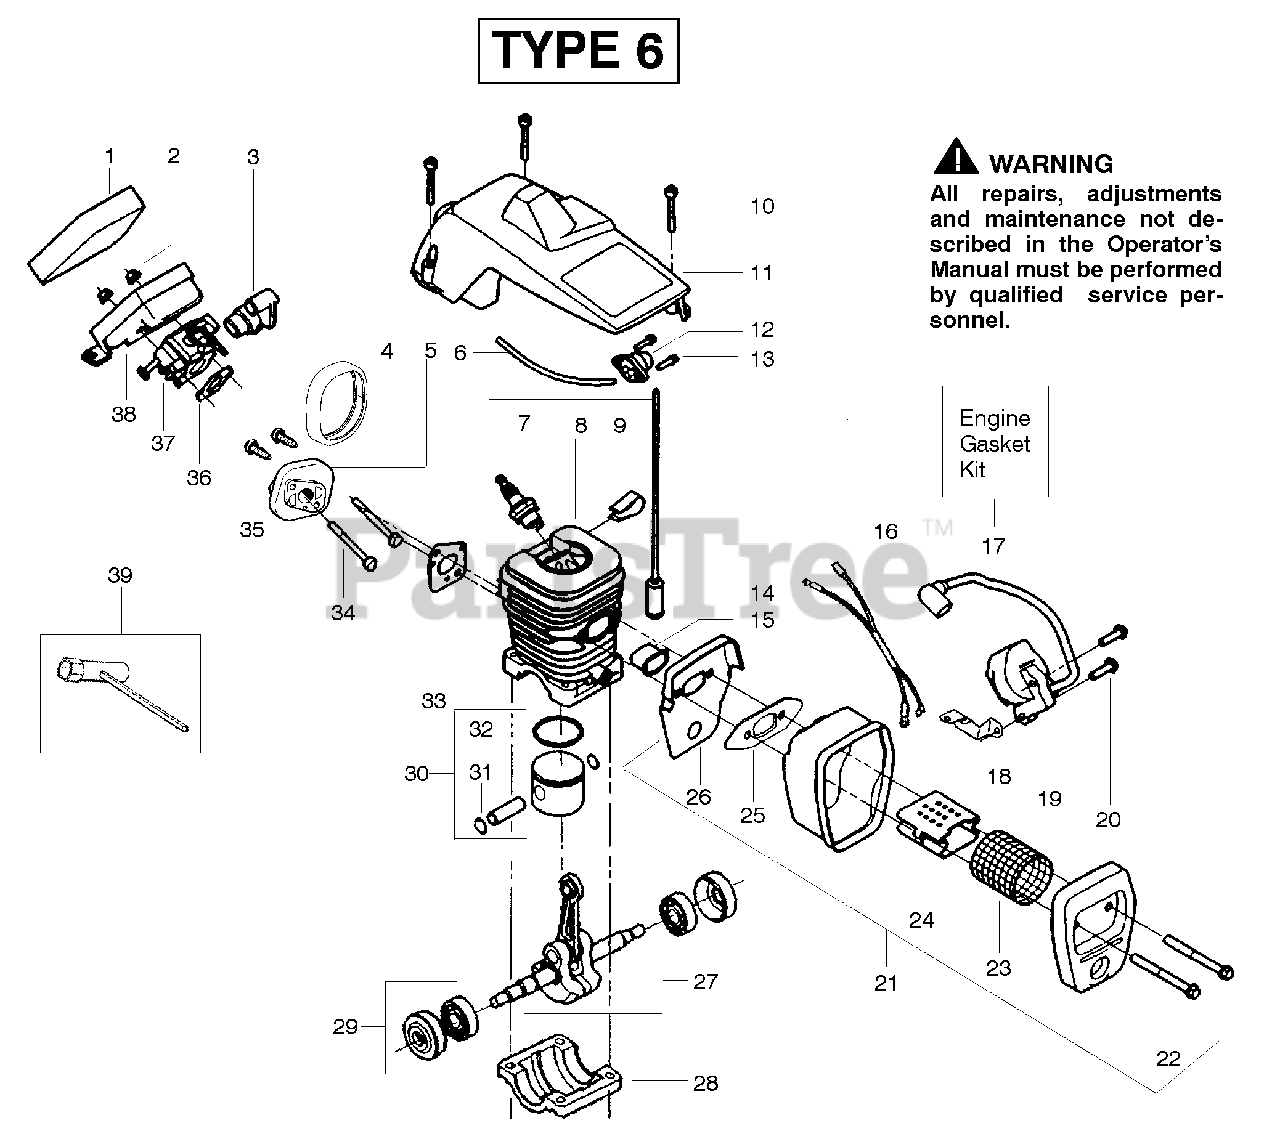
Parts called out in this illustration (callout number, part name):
1	Foam- Air Filter
3	Grommet-Carb Adjust
4	Seal-Carb Adapter
5	Adapter-Carb.
6	Kit-Fuel Line (Small)
7	Spark Plug (RCJ-7Y)
8	Kit-Cylinder
9	Clip-High Tension Lead
11	Shield-Cylinder
12	Assy- Air Purge
14	Assy-Fuel Pick-up
15	Insulator-Heat
16	Assy. -Wire Harness
17	Kit-Engine Gasket
18	Strap-Ground
19	Module- Ignition
21	Assy-Muffler
23	Screen-Spark
24	Diffuser-Muffler
25	Gasket-Muffler(kit)
26	Backplate-Muffler
27	Assy. - Crankshaft
28	Cap-Crankcase
29	Assy.-Seal & Bearing
30	Kit-Piston
31	Retainer-Piston Pin
32	Ring - Piston
33	Gasket - Adapter(kit)
36	Gasket - Carb.(kit)
37	Kit-Carburetor (WT-624)
38	Housing- Air Filter
39	Wrench - Bar
